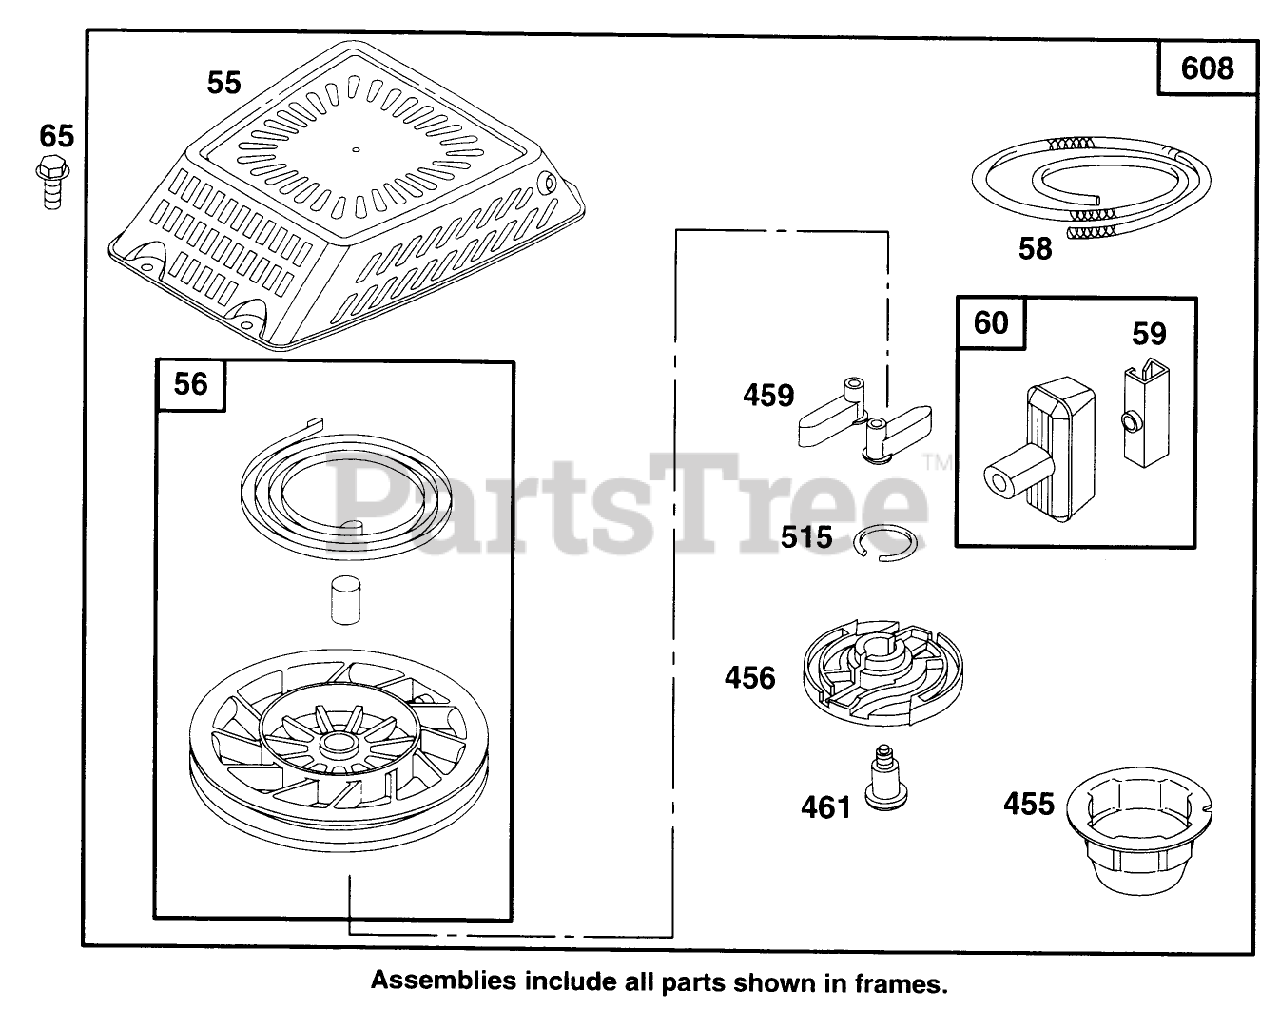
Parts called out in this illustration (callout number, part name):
56	PULLEY-STARTER, REWIND
59	INSERT-HANDLE, REWIND
455	CUP - STARTER
456	RETAINER-STARTER, REWIND
459	PAWL-STARTER
515	SPRING-TORSION
608	BRIGGS #498146
